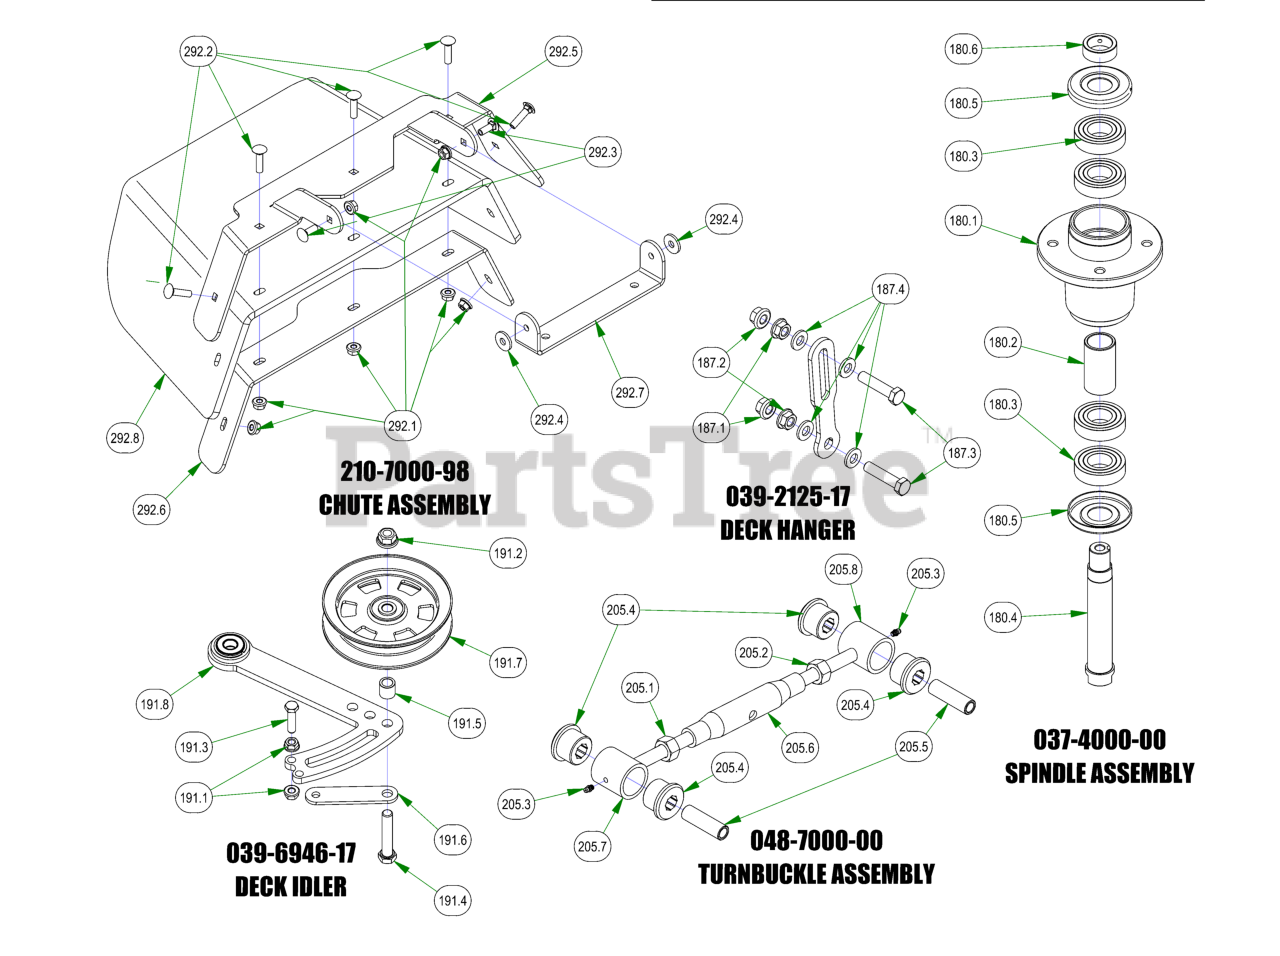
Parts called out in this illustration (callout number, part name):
180	OUTLAW SPINDLE ASSEMBLY
180.1	4000 Series Spindle Housing
180.2	4000 Series Spindle Spacer
180.3	Bearing - 6206
180.4	Spindle Shaft
180.5	Spindle Dust Cap
180.6	Locking Collar w/ 1/4"-20 Set Screw
187	Deck Hanger Assembly
187.1	1/2-13 HEX SERRATED FLANGE NUT HARD/ZINC
187.2	1/2-13 NYLON INSERT FLANGE LOCKNUT ZINC
187.3	1/2-13 X 2-1/4 HEX CAP SCREW (GR.5) ZINC
187.4	.505 ID X 1.000 OD X .125 THICK FLAT WASHER NYLON
187.5	Deck Hangar
191	2019 Renegade Deck Idler
191.1	3/8-16 HEX SERRATED FLANGE NUT HARD/ZINC
191.2	1/2-13 NYLON INSERT FLANGE LOCKNUT ZINC
191.3	3/8-16 X 1-1/2 HEX CAP SCREW (GR.5) ZINC
191.4	1/2-13 X 2-3/4 HEX CAP SCREW (GR.5) ZINC
191.5	.51 ID X .75 OD X .75 LGTH SOLID SPACER ZINC
191.6	Belt Tensioner Retainer Plate
191.7	5" Idler Pully
191.8	2019 Deck Tensioner
205	Turnbuckle
205.1	11/16-12 Hex Nut-2015 Toplink
205.2	11/16-12 Lefthand Hex Nut-Topl
205.3	1/4" Press in Grease Fitting
205.4	Polyeurethane Bushing
205.6	2015 Outlaw Toplink Body
205.7	2015 Outlaw Toplink RH End
205.8	2015 Outlaw Toplink LH End
292	2019 Outlaw Gen2 Chute Assembly
292.1	5/16-18 NYLON INSERT FLANGE LOCKNUT ZINC
292.2	5/16-18 X 1-1/4 CARRIAGE BOLT ZINC
292.3	5/16-18 X 7/8 CARRIAGE BOLT ZINC
292.4	.360 ID X .983 OD X .120 THICK FLAT WASHER NYLON
292.5	2019 Upper Chute Bracket
292.6	2019 Lower Chute Bracket
292.7	2019 Chute Hanger
292.8	2019 Belted Chute with Logo
